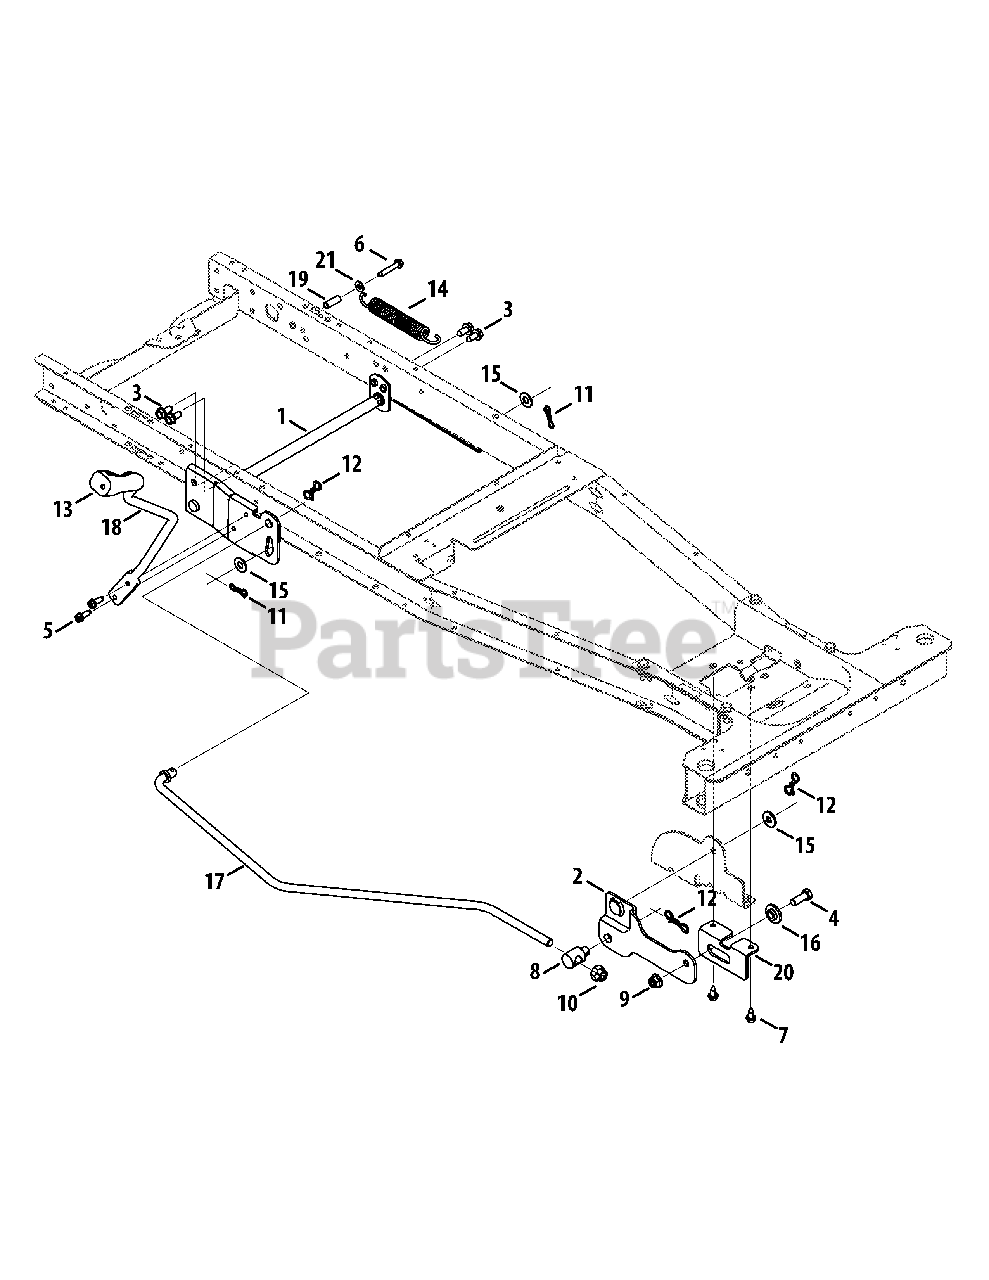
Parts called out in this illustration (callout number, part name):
1	Lift Assembly Shaft
2	Front Hanger Bracket Assembly
3	Tap Screw, 5/16-18, .750
4	Hex Head Screw, 3/8-16, 1.00
5	Tap Screw, 1/4-20, 0.750
6	Screw, 1/4-20, 1.50
7	Tap Screw, 1/4-20 X .625
8	Ferrule, .50 X .50
9	Flange Lock Nut, 3/8-16
10	Hex Lock Nut, 1/2-13
11	Bow-Tie Cotter Pin, 72
12	Bow-Tie Cotter Pin, 91
13	Grip Handle, 1/2
14	Extension Spring, .85 OD X 5.915 LG
15	Flat Washer, .406 X .875 X .059
16	Shoulder Spacer, .625 ID X .169
17	Lift Link Rod
18	Deck Lift Rod
19	Spacer, .260 x .375 x 1.030 LG
20	Front Deck Mounting Bracket
21	Flat Washer, .250 x .630 x .052
